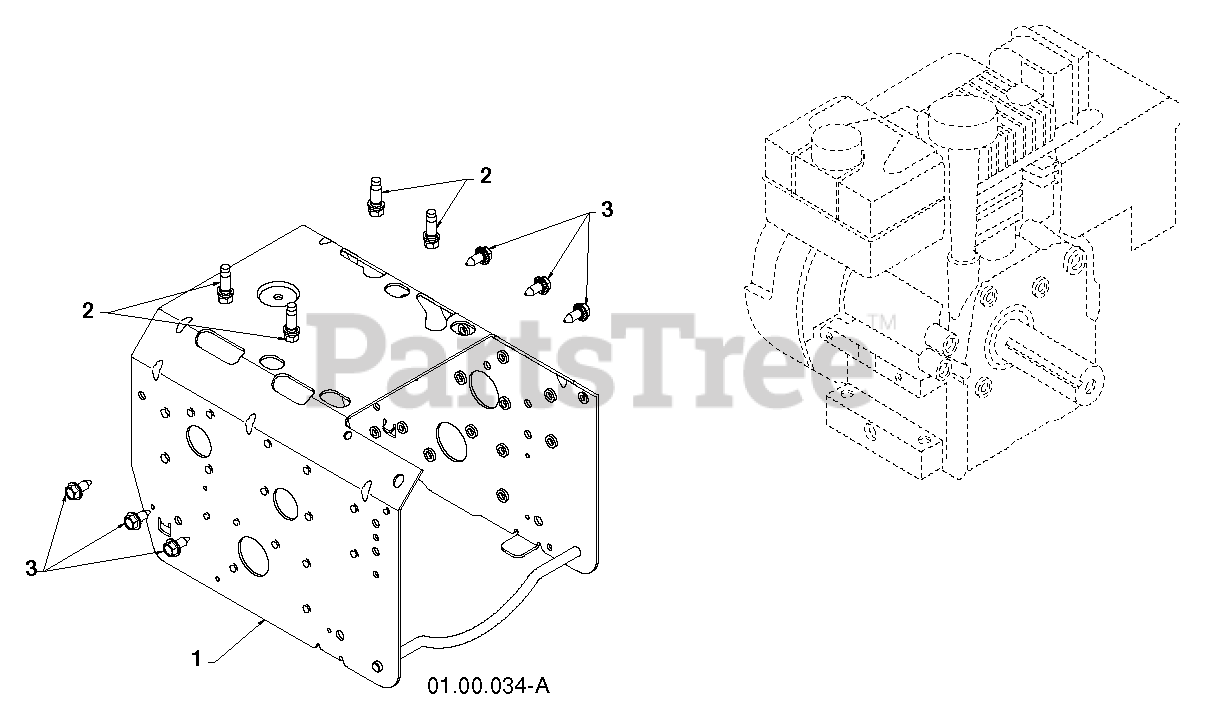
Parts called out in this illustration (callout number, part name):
1	FRAME.WELD.PNT.CHAIN.ORANGE
2	BOLT 3/8-16X1-1/8
3	BOLT.HEX.HD.WASHER.5/16-18X.75
